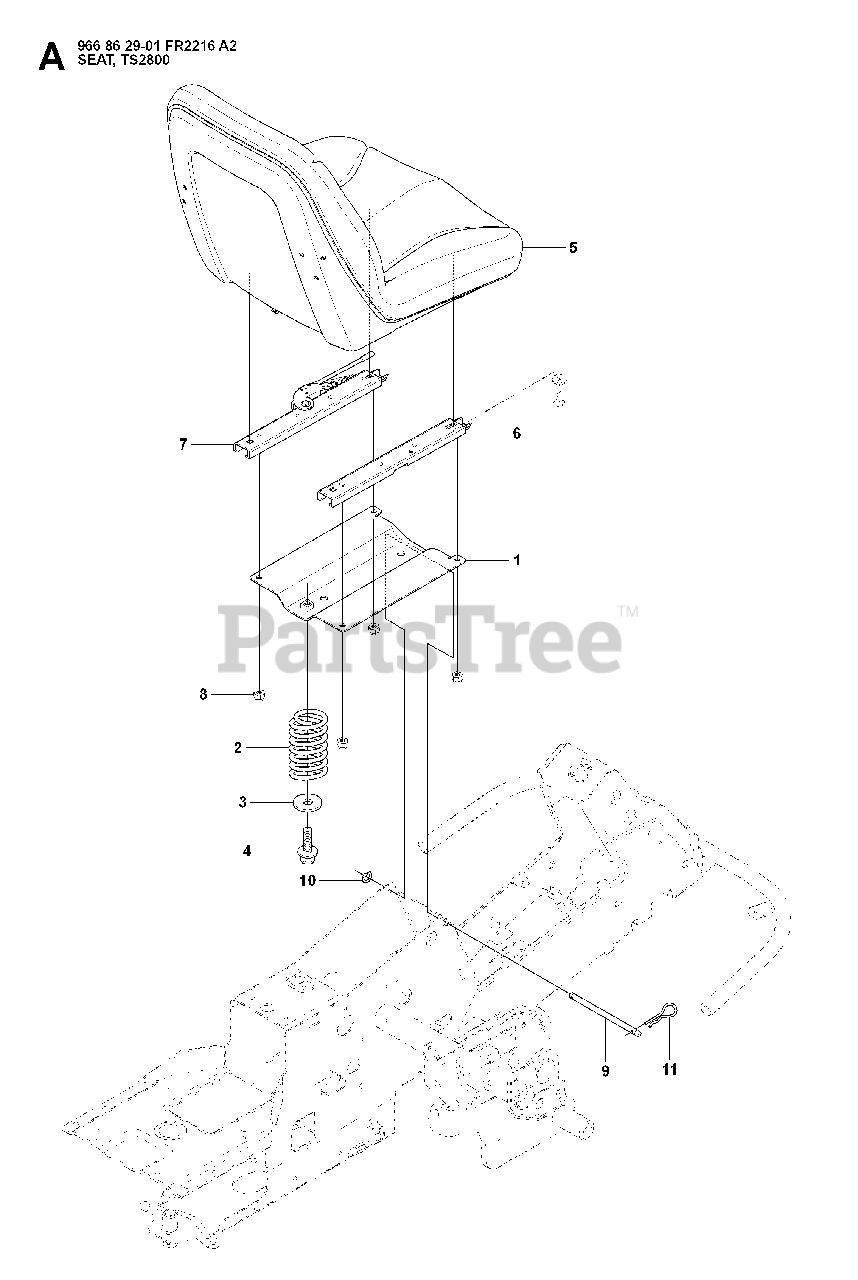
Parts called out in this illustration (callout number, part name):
2	SEAT SPRING
4	SCREW M10X25
8	LOCKNUT M8
10	RETAINING RING SGA 10
